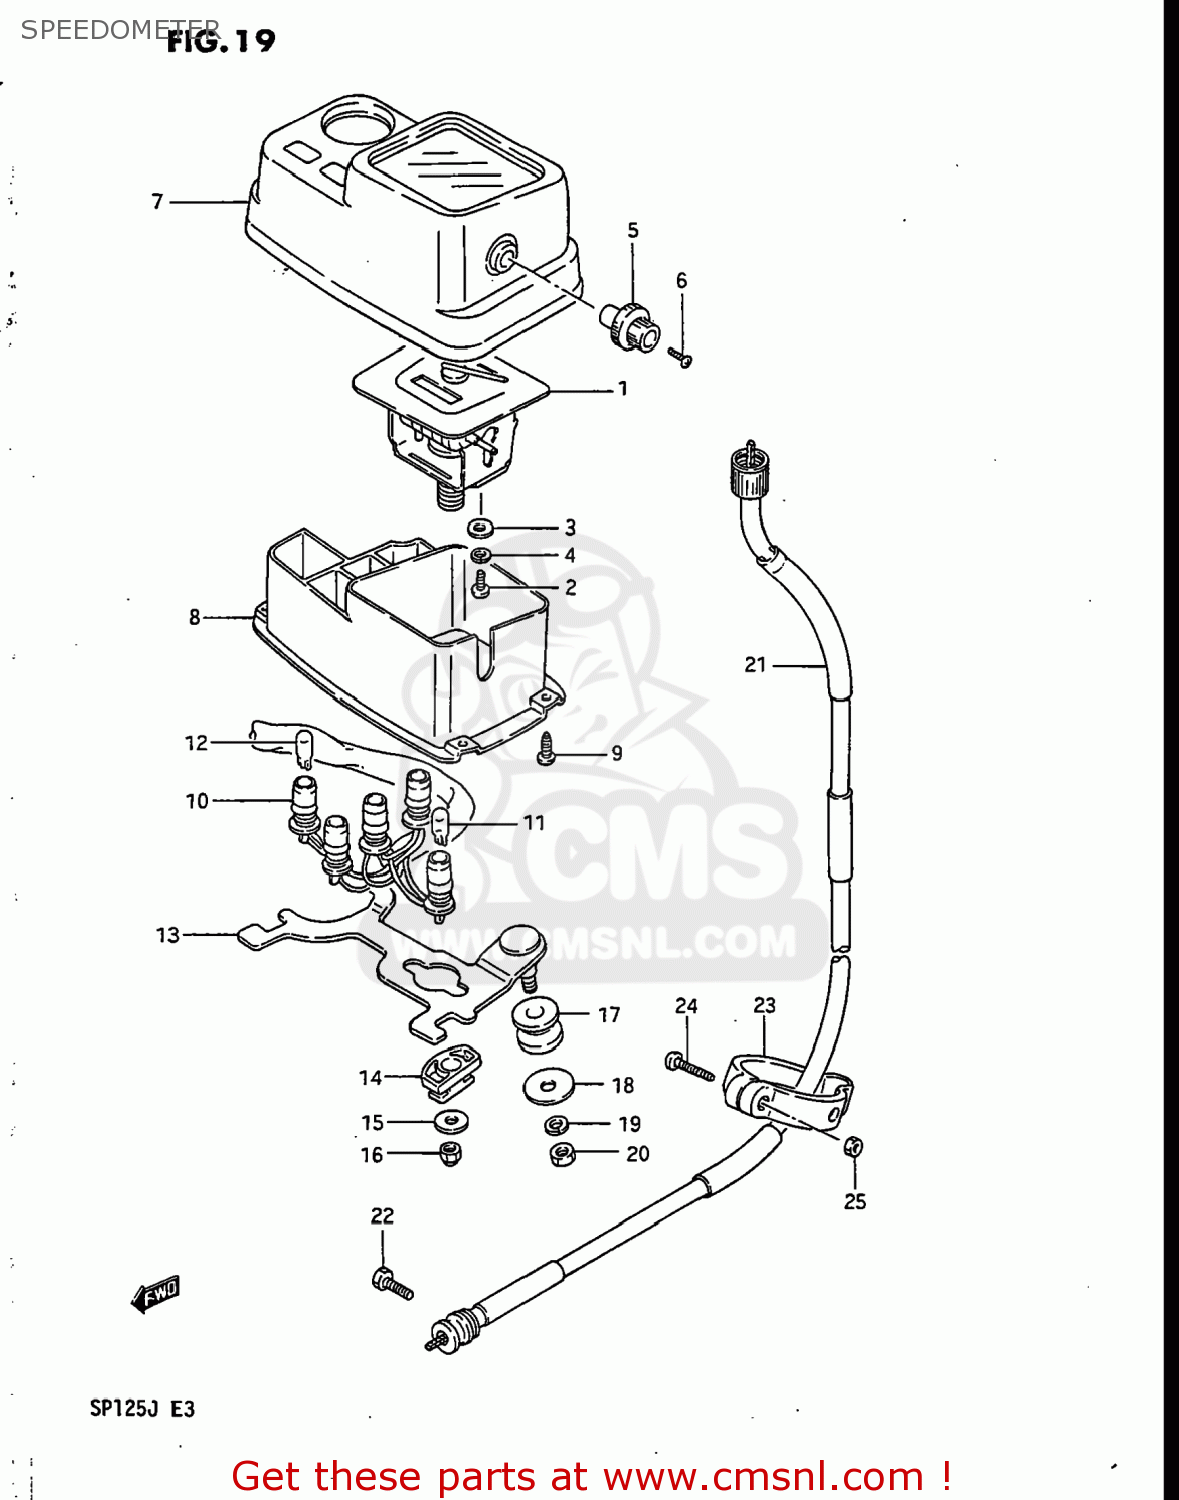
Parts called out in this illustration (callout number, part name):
1	SPEEDOMETER (MILE/KILO)
2	SCREW
3	WASHER
4	LOCK WASHER
5	KNOB,TRIP
6	ROTOR,SPEED
7	HOOD,METER
8	CASE,METER
9	SCREW
10	SOCKET,METER
11	BULB(6V,3W)
12	BULB(6V1.7W,STANLEY,A61A)
13	BRACKET,METER
14	CUSHION
15	WASHER
16	NUT
17	CUSHION
18	WASHER
19	WASHER,LOCK
20	NUT
21	CABLE ASSEMBLY,SPEEDOMETER
22	BOLT
23	CLAMP,SPEEDOMETER CABLE
24	SCREW
25	NUT ,5MM
